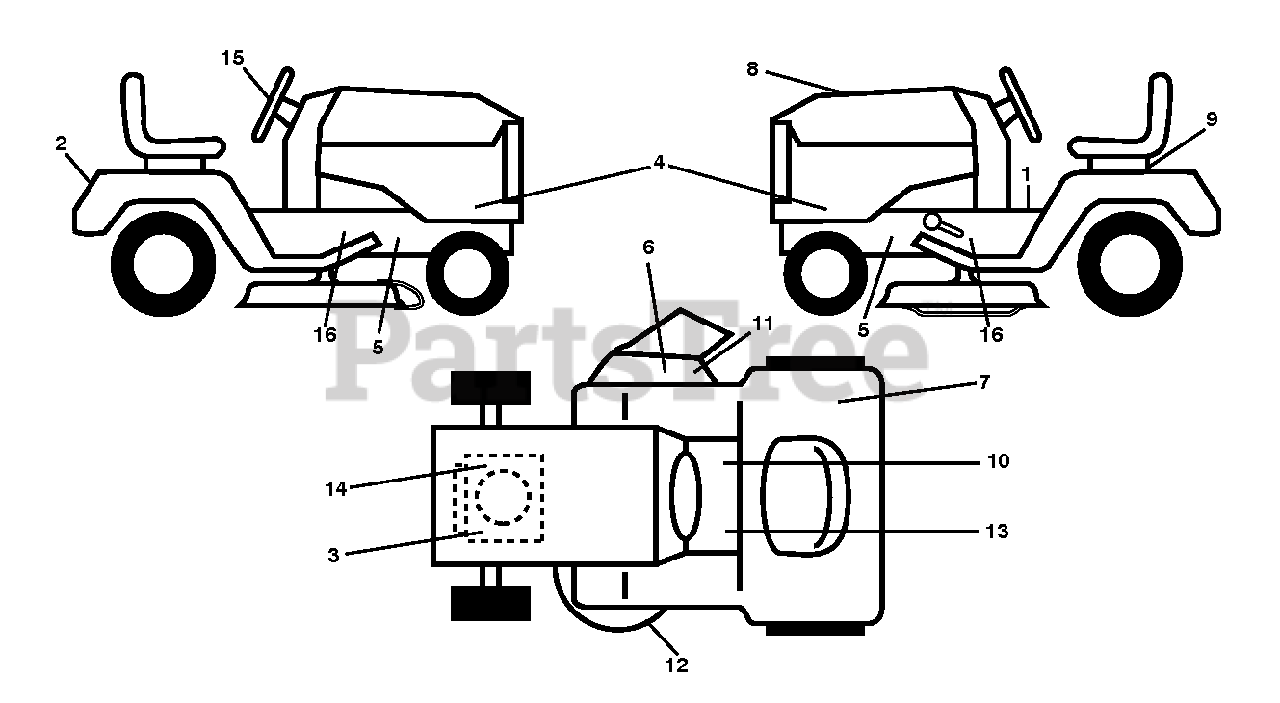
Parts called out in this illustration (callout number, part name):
4	DECAL.SDPNL.LT2313A.BRIGGS.JON
9	DECAL BTRY SYMBOLS
11	DECAL, DECK DEFLECTOR, WARNING
12	DECAL.DECK.SCH.3638
14	DECAL.ENG.BS.3125SER.PB.279738
